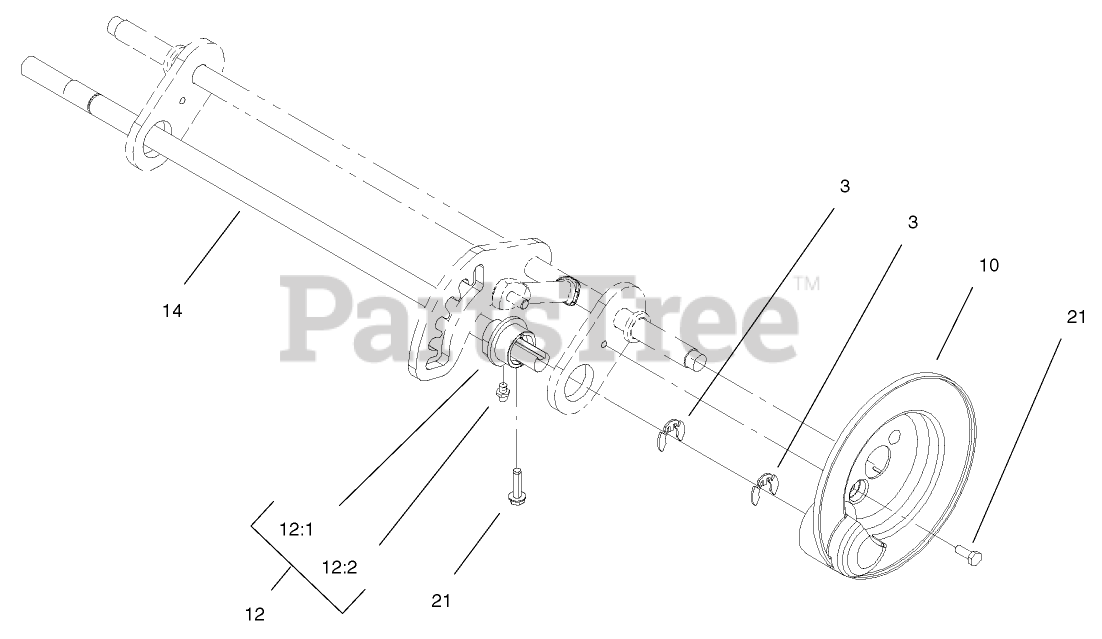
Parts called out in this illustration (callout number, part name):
3	RING-RETAINING,CLIP
10	COVER-GEAR
12	BUSHING ASM
12:2	FITTING-GREASE
14	SHAFT-PIVOT
21	SCREW-TAPTITE
